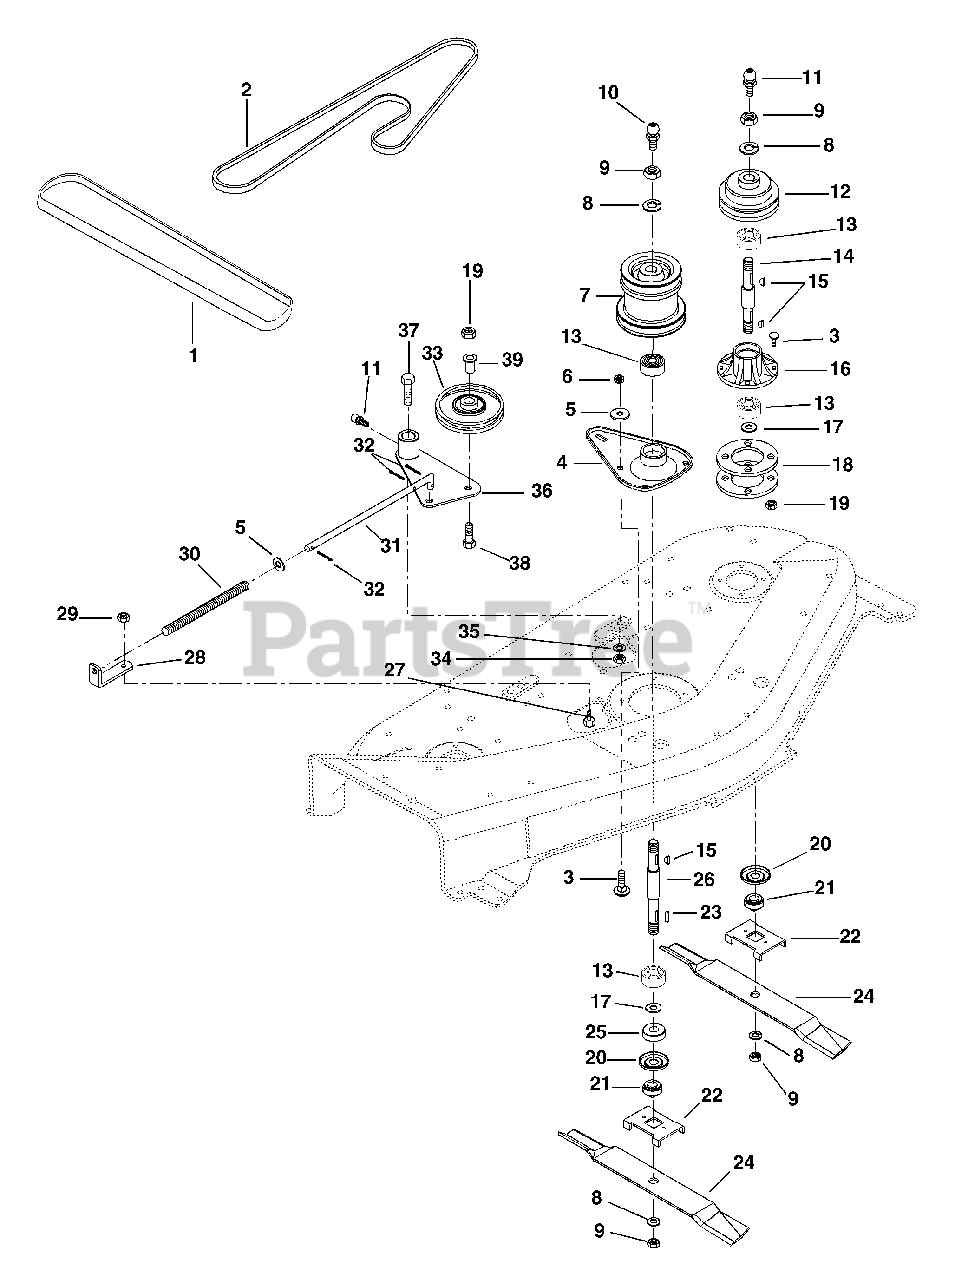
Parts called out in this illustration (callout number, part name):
1	Belt, 48" Clutch to Deck
2	Belt, 48" EZR Deck
3	Bolt-Round Head Square Neck .38-16 x .75
4	Housing, Spindle
5	Washer-Flat-Steel .406 x .812 x .065
6	Nut-Locking-Center .375-16
7	Sheave, 48" Deck
8	Washer-Lock .750 x .188
9	Nut-Jam .75-10
10	Fitting, Lube .125
11	Fitting, Lube .25-28 x .256
13	Bearing-Ball .750 x 1.781 x .61
14	Spindle Shaft w/Zerk
15	Key-Woodruff .188 x .62 x .25
16	Spindle Housing
17	Washer-Flat-Steel .754 x 1.000 x .032
18	Spacer, Spindle
19	Nut-Locking-Jam - .375-16
20	Bearing Slinger
21	Retainer Hub
22	Blade Tray 48
23	Key-Square .188 x .625 x .188
24	Blade
25	Washer-Flat-Steel .755 x 1.250 x .125
26	Spindle Shaft w/Zerk & Key
27	Bolt-Hex .31-18 x .50 Grade 5
29	Nut-Locking-Center .312-18
30	Spring-Compression .106 x .63 x 12.0
31	Rod-Idler Spring
32	Pin-Cotter .09 x .75
33	Idler-Plastic 4.75 OD x .50 ID
34	Nut-Locking-Center .50-13
35	Washer-Flat-Steel .505 x .880 x .072
36	Idler Arm w/Zerk
37	Bolt-Hex .50-13 x 1.50
38	Bolt-Button Head .38-16 x 1.25 Grade 5
39	Spacer-Flanged .390 x .500 x .781 x .875
